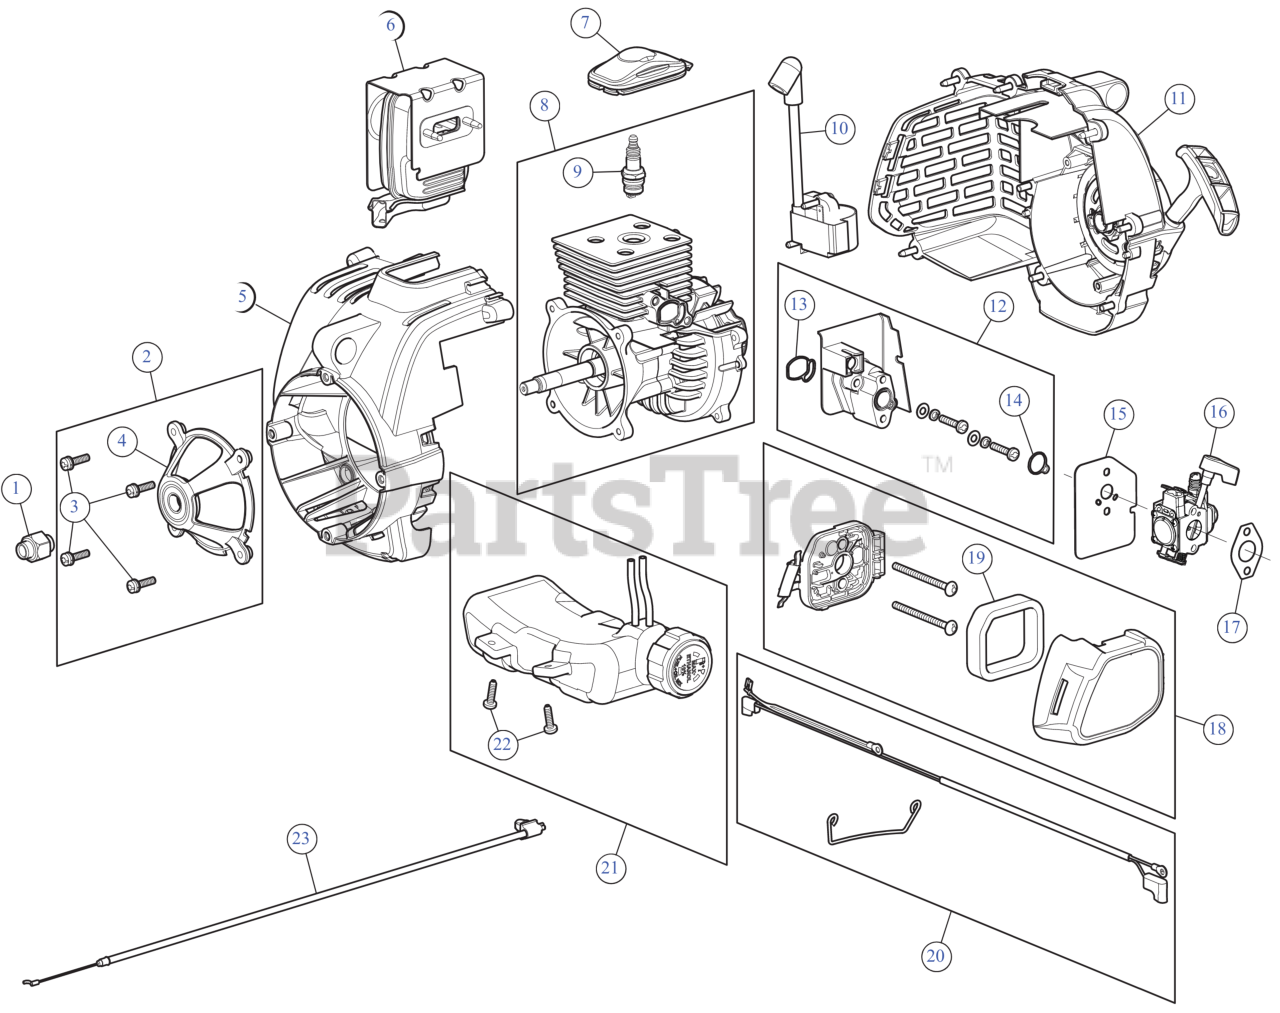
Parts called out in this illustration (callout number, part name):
1	FLYWHEEL ADPT
2	BEARING HLDR ASSEMBLY
3	SCREW M5X0.8-20
4	BEARING HOLDER
5	ENGINE COVER FRT
6	MUFFLER ASSEMBLY
7	SPARK PLUG COVER
8	SHORT BLOCK
9	SPARK PLUG
10	MODULE BLOWER
11	COVER ASSEMBLY EGINE RR
12	INTAKE ASSEMBLY BLOWER
15	CARBURETOR GASKET
16	CARBURETOR
17	GASKET CARB
18	AIRCLEANER COVER ASSEMBLY
19	AIR FLITER
20	WIRE LEAD BLOWER
21	FUEL TANK ASSEMBLY
22	SCREW:10-6 x .75
23	THROTTLE CABLE
